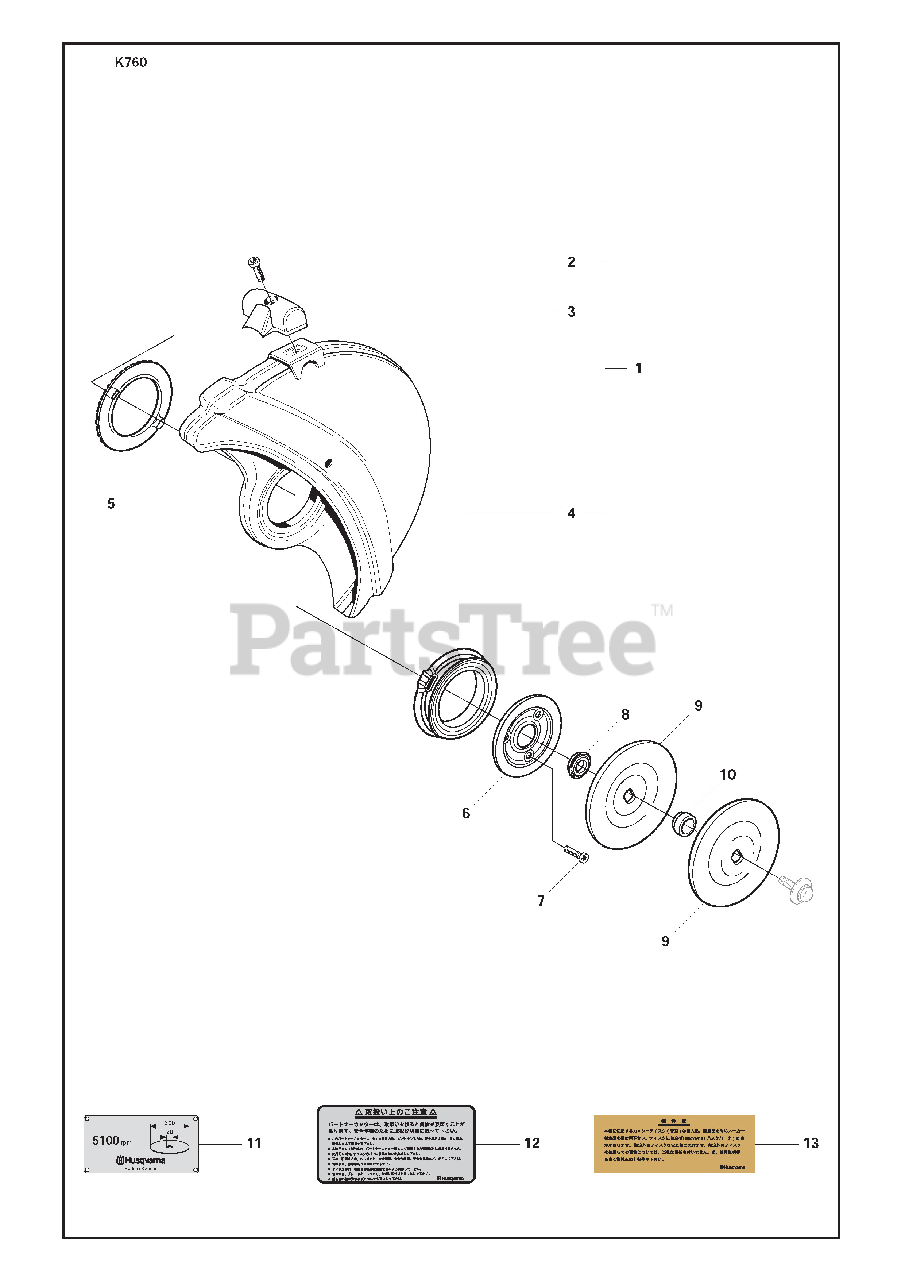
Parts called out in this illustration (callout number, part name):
1	WHEEL GUARD ASSY, 12" GREY
1	WHEEL GUARD ASSY
7	SCREW ITXSCM
9	WASHER
10	BUSHING
10	BUSHING-30MM
11	LABEL
11	Label
11	ARBOR SIZE DECAL/25.4
11	ARBOR SIZE DECAL/20
12	Label
13	Label
